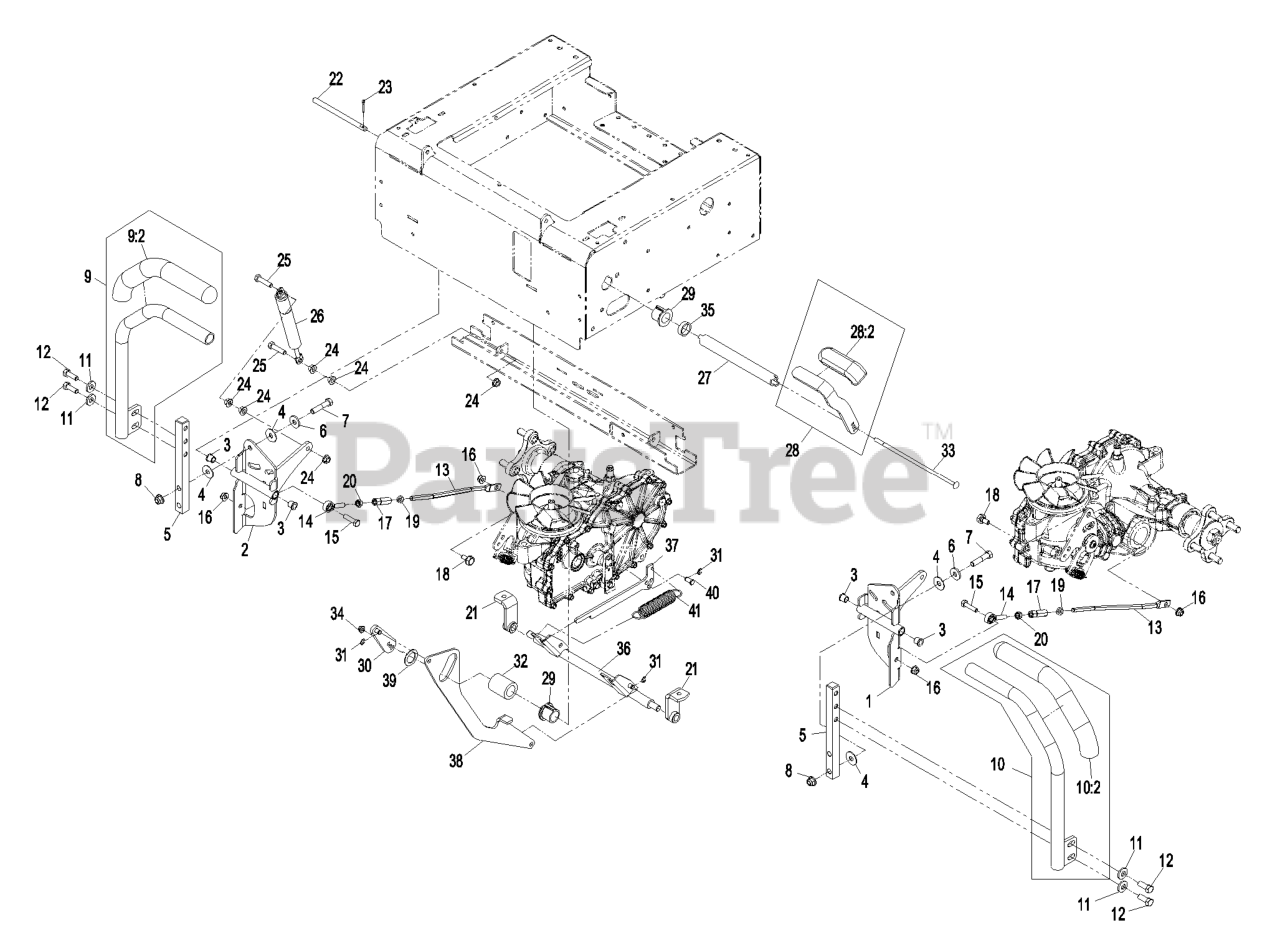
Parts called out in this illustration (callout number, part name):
1	LH MOTION CONTROL PIVOT A
2	RH MOTION CONTROL PIVOT A
3	BEARING
4	WASHER-PLASTIC
5	POST-LEVER MOUNT
6	WASHER
7	SCREW-HH
8	NUT-HF, NI
9	RH LEVER AND GRIP ASM
9:2	GRIP-CONTROL LEVER
10	LH LEVER AND GRIP ASM
10:2	GRIP-CONTROL LEVER
11	WASHER-BELLEVILLE
12	SCREW-HH
13	ROD-STEERING
14	BEARING-ROD END, LH
15	SCREW-HH
16	NUT-HF, NI
17	NUT-ROD ADJUSTMENT
18	BOLT-SHOULDER,HFH
19	NUT-JAM
20	NUT-JAM
21	BRAKE PIVOT ASM
22	PIN-CONTROL PIVOT
23	PIN-COTTER
25	SCREW-HH
26	DAMPER-MOTION CONTROL
27	TUBE-BRAKE PIVOT
28	LEVER ASM
28:2	GRIP-LEVER
29	BUSHING-FLANGE, KEYED
30	BELLCRANK ASM
31	E-RING
33	BOLT-CARR
36	BRAKE SHAFT ASM
37	LINK-BRAKE ACTUATION
38	ARM-BRAKE
40	PIN-CLEVIS
41	SPRING-EXTENSION
